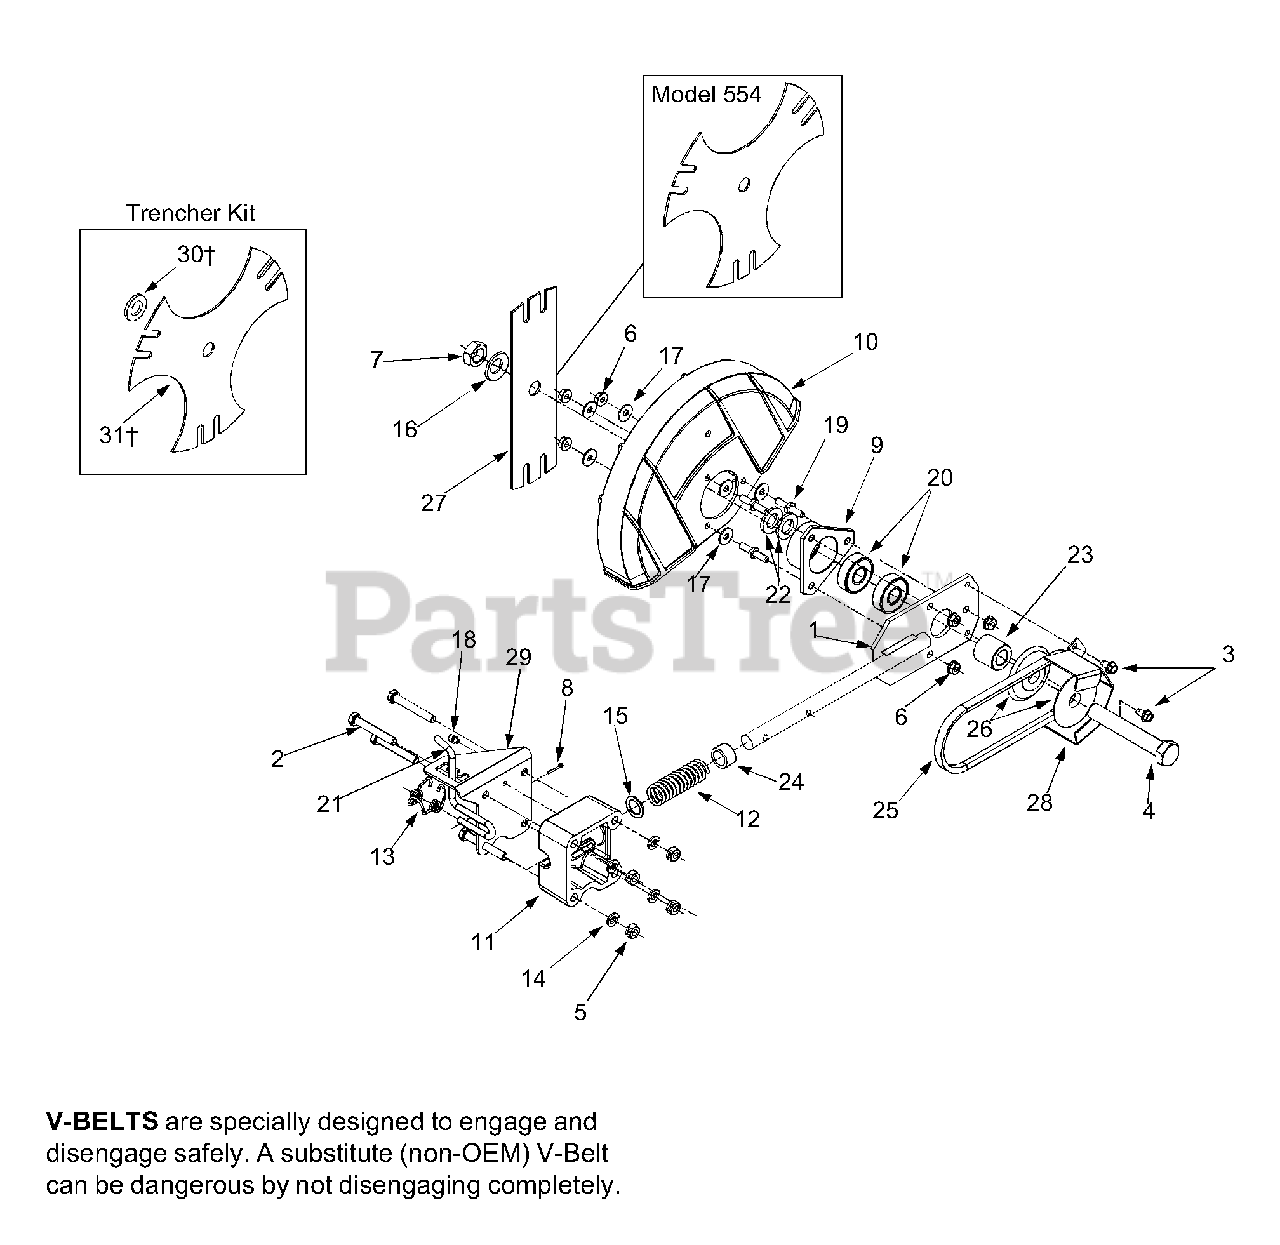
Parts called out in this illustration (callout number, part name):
1	Blade Plate Assembly
2	Hex Screw, 5/16-18
3	Self-tapping Screw, 1/4-20
4	Hex Screw, 5/8-18
5	Hex Lock Nut, 5/16-18
6	Hex Flange Nut, 1/4-20
7	Jam Nut, 5/8-18
8	Cotter Pin
9	Bearing Cup
10	Blade Guard
11	Bearing Block
12	Compression Spring
13	Double Torsion Spring
14	Lock Washer
15	Flat Washer
16	Bell Washer,.63 ID x 1.2 OD
17	Flat Washer,.260 x.72
18	Lube Fitting, 3/16
19	Pin, 1/4-20
20	Bearing,.625 ID x 1.57 OD
21	Blade Adjustment Rod
22	Flat Washer,.635 x 1.2
23	Spacer,.63 x 1.12 x 1.06
24	Spacer,.632 ID x.875 OD
25	Belt
26	Sheave
30	Flat Washer
